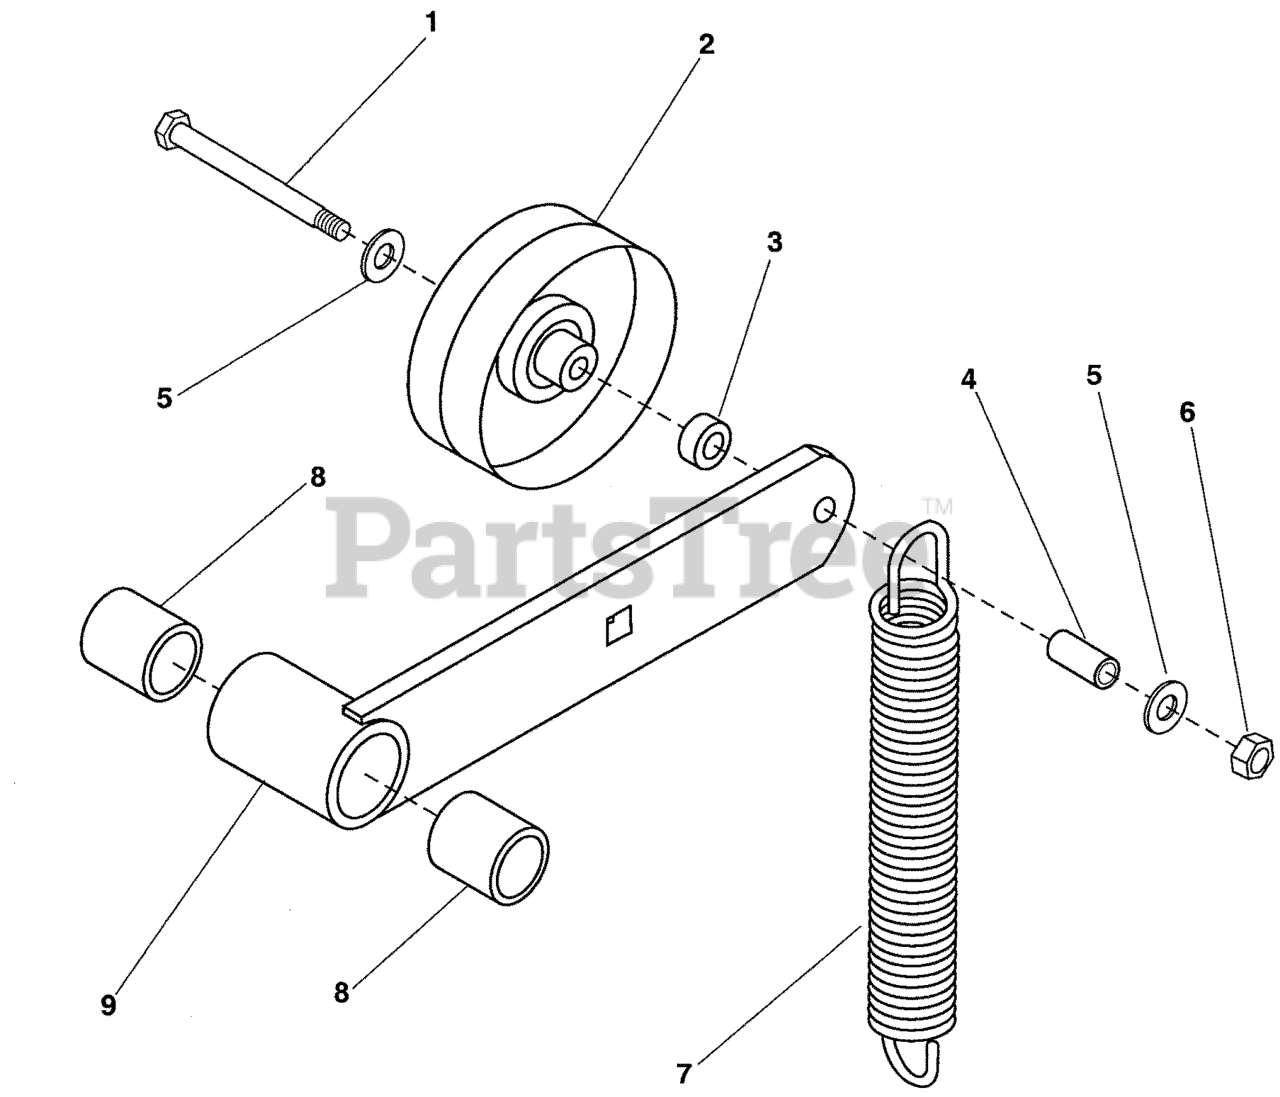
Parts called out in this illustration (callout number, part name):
1	BOLT, 3/8-16 X 4" GD5 CZ
2	PULLEY, Flat Idler
3	SPACER
4	SHOCK MOUNT
5	WASHER, 3/8 SAE
6	NUT, 3/8-16 HEX NYLON LOCK
8	BUSHING, Flange
9	IDLER ARM
